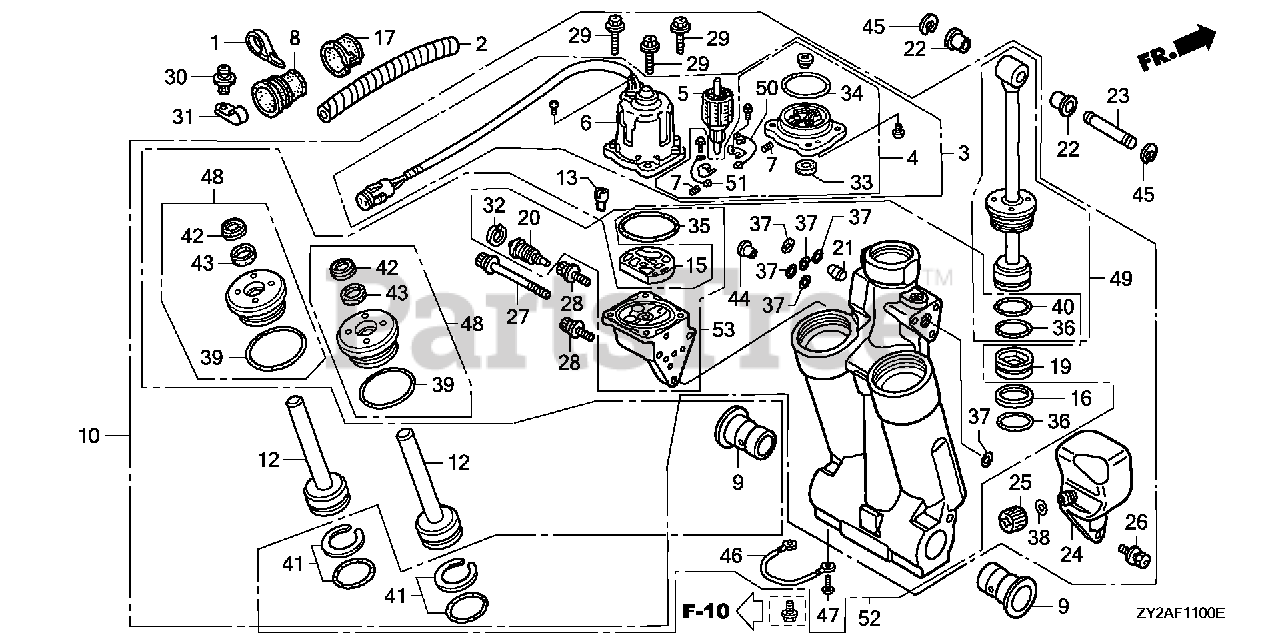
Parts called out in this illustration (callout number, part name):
1	BAND (BLACK 3.5X140)
2	TUBE, SPIRAL (12X14.6)
3	MOTOR ASSY., POWER TILT
4	BRACKET ASSY.
7	SPRING, MOTOR
8	GROMMET, CASE (LOWER) (C)
9	BUSH, SWIVEL CASE
10	TRIM-TILT ASSY., POWER
11	PUMP ASSY.
12	ROD, PISTON (B)
13	JOINT, DRIVE
14	GUIDE, ROD
16	RING, BACK-UP
17	BUSH, MOTOR CODE
18	ROD, PISTON
19	PISTON, FREE
20	VALVE, MANUAL
21	VALVE, RESERVOIR
22	BUSH, CYLINDER (LOWER)
23	PIN, CYLINDER (UPPER)
24	TANK, OIL
25	CAP, OIL TANK
26	BOLT, RECESSED
27	BOLT A, SOCKET
28	BOLT B, SOCKET
29	BOLT, HEX.
30	SCREW, RIVET (5X10)
31	CLIP (10.7MM)
32	CIRCLIP (INNER)
34	O-RING (2.0X70.5)
35	O-RING (1.8X69.6)
36	O-RING (3.5X38.7)
37	O-RING (1.8X7.7)
38	O-RING (1.9X11)
39	O-RING (3.5X35.7)
40	O-RING (3.5X41.7)
41	O-RING SET (3.5X31.7)
42	SEAL, WATER
44	COLLAR, ORIFICE
45	E-RING (15MM)
46	WIRE, LEAD (1.5X116MM)
47	SCREW, PAN (6X8)
48	GUIDE, ROD
49	ROD, PISTON
50	BREAKER ASSY.
51	BRUSH ASSY.
53	PUMP ASSY.
